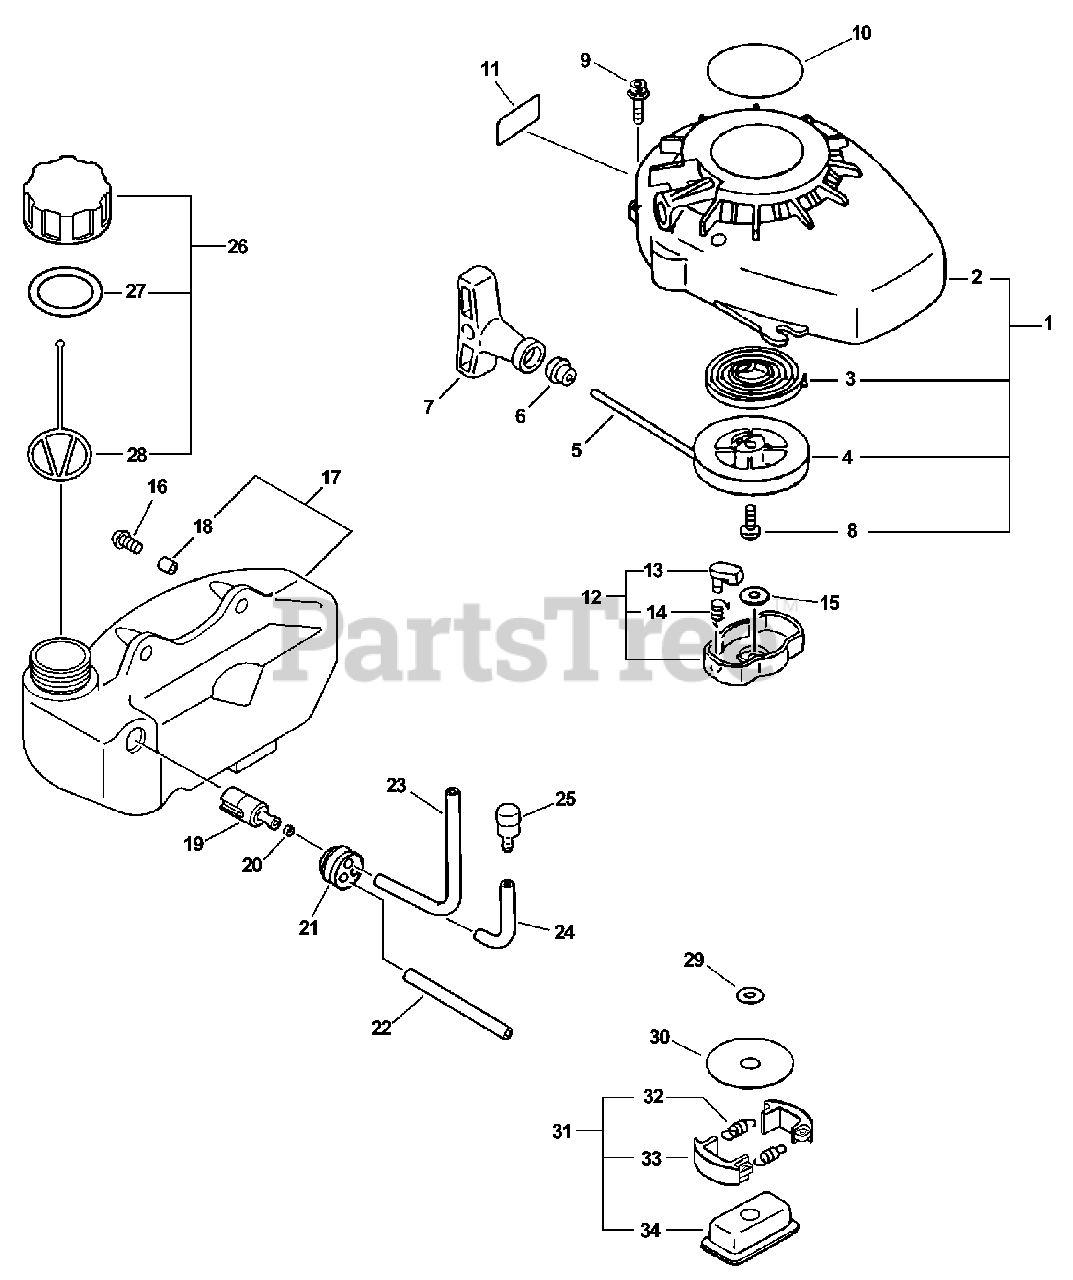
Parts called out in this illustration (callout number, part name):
1	STARTER ASSY
2	CASE, FAN
3	SPRING, REWIND
4	REEL, ROPE
5	ROPE, STARTER - 3X1000
6	GUIDE, ROPE
7	GRIP, STARTER
9	SCREW - 4X16
10	LABEL - MODEL HC-150
10	LABEL - MODEL HCR-150
11	LABEL - CAUTION
12	STARTER PAWL ASSY
13	PAWL, STARTER - BLACK
14	SPRING, RETURN
15	LOCKWASHER - 8
16	SCREW - 5X15
17	TANK, FUEL
19	FILTER, FUEL
20	CLIP - 6
21	GROMMET
22	PIPE - 3X6X110 -- CLEAR
23	PIPE - 3X5X195 -- BLACK
24	PIPE - 3X5X70 -- BLACK
25	VENT, FUEL TANK
26	CAP ASSY - ORANGE
27	GASKET, CAP
28	CONNECTOR, CAP
29	WASHER, CLUTCH
30	PLATE, CLUTCH
31	CLUTCH ASSY
32	SPRING, CLUTCH
33	SHOE, CLUTCH
34	HUB, CLUTCH
